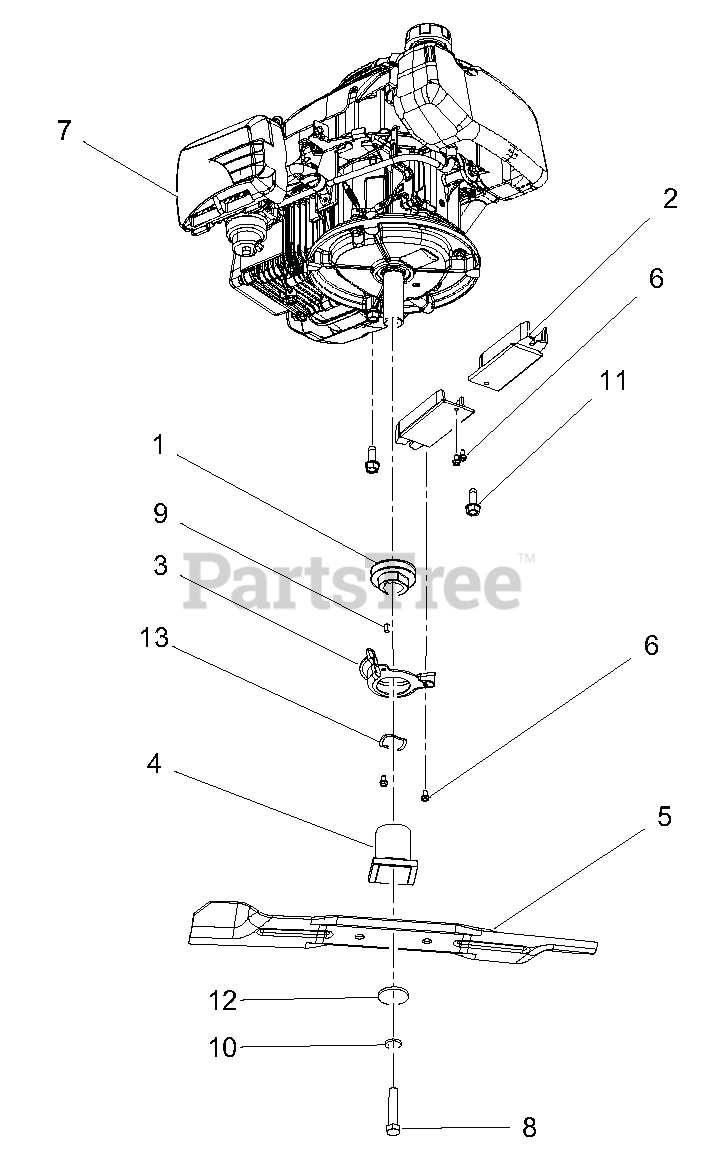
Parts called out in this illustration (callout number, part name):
1	PULLEY, GROUND DRIVE, LM
2	GUIDE, BELT INNER
3	GUIDE, BELT CRANK
4	ADAPTER, BLADE
5	BLADE, MOWER 21" HIGH LIFT
6	SCR-TAP 10-24X.375 PRE-COAT 80
7	ENGINE, SUBARU 175CC VERT
7	ENGINE, SUBARU 175CC VERT. ES
8	@BLT-HEX .4375-20X2.25 GR8 YWZ
9	KEY-SQ .188X.188X.625
10	@WSHR-LK .44X.109 REG YWZC
11	@SCR-TAP .38-16X1.00 HWH TR YZ
12	WSHR-FL-STL .4375X1.50X.125 YZ
13	WASHER - WAVE 1.09X1.37X.016
